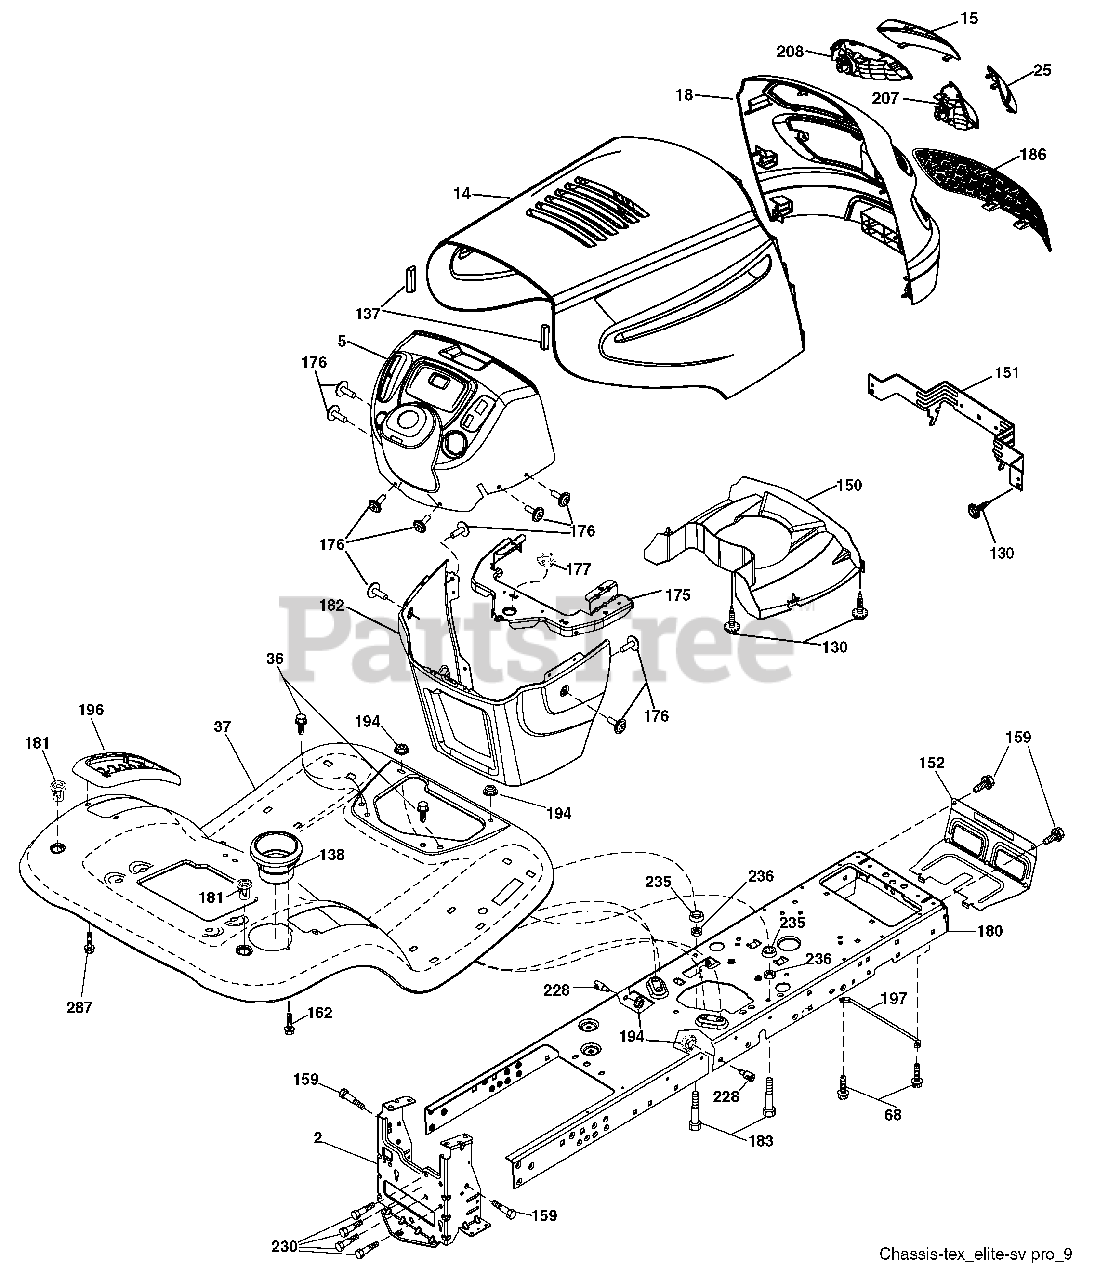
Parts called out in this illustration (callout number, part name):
2	Drawbar
5	Dash
14	Hood
15	Lens Grille LH
18	Grille
25	Lens Grille RH
36	Screw 5/16-18 x 3/4
37	Fender
68	Screw Thdrol 5/16-18 x 1/2
130	Screw #10 x 0.750 ROS Thread
137	Bumper Hood
138	Cupholder
150	Duct Heat Hood
151	Bracket Pivot
152	Shield Browning/Debris
159	Screw Hexwsh Thdrol 3/8-16 x 3/4
162	Screw Hex Wsh Hi-Lo 1/4 x 1/2
175	Crossmember
176	Screw 10-24 x 5/8 Wshd Qdrx
177	Bushing Steering
181	Bushing Mtg. Fender Crgo.
182	Dash Lower
183	Bolt Fin Hex 5/16-18 x 1-1/4
194	Nut Lock Hex Flange 5/16-18
196	Console Asm. Deck Lift
197	Rod Pivot Chassis
207	Bezel Grille RH
208	Bezel Grille LH
228	Stud Fastener
230	Bolt Shoulder 5/16-18
235	Spacer Fender
236	Nut center Lock 5/16-18
287	Screw Hex Washead 1/4-20 x 3/8
